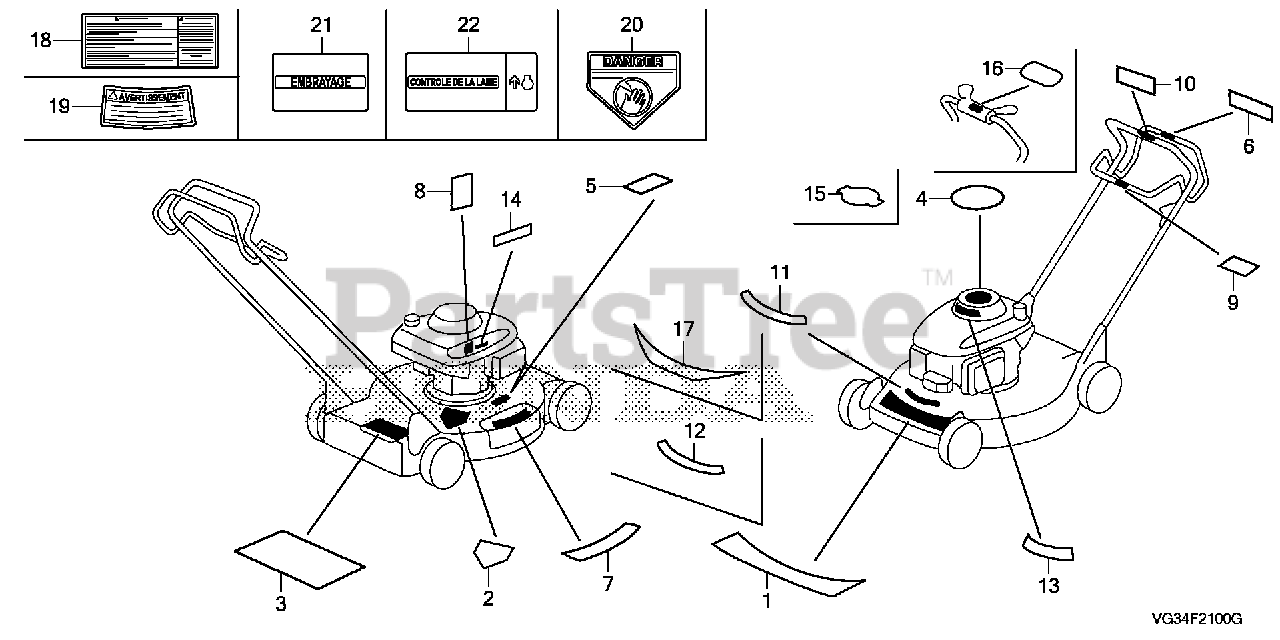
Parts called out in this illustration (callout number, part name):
2	LABEL C, HOUSING CAUTION
3	LABEL, WARNING (ENGLISH)
5	LABEL, HEAT WARNING
7	LABEL, DISCHARGE GUARD WARNING (ENGLISH)
9	MARK, BLADE CONTROL (ENGLISH)
11	MARK, MODEL (HARMONY S)
12	MARK, HONDA
15	MARK, RECOIL COVER
